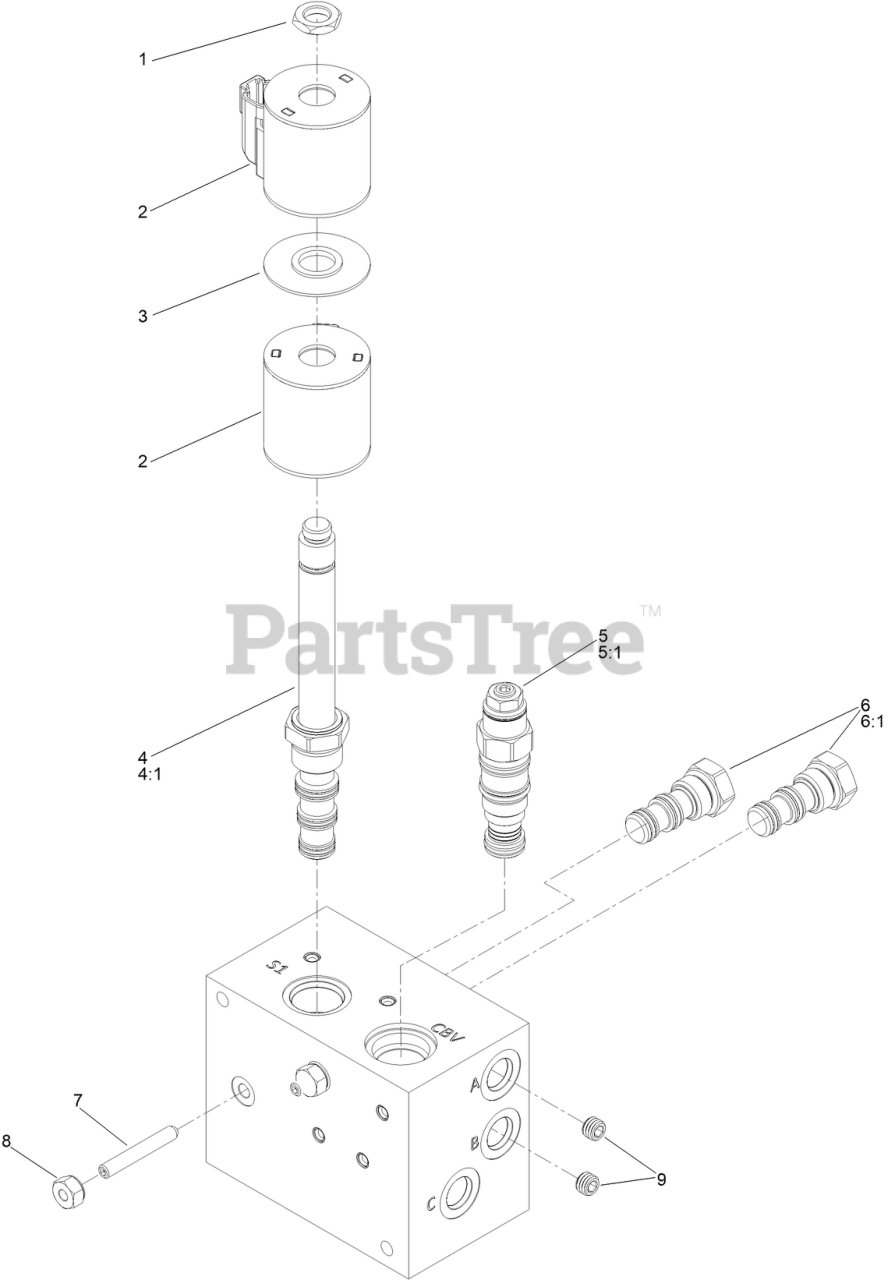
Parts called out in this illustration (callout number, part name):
1	NUT-COIL
2	COIL-12V
3	SPACER-E COIL
4	SOLENOID VALVE ASM
4:1	SPOOL VALVE SEAL KIT
5	VALVE-COUNTERBALANCE
5:1	SEAL KIT
6	PO CHECK VALVE
6:1	SEAL KIT
7	SCREW-SET
8	NUT-SEALING, HEX
9	PLUG-ORIFICE (0.020)
